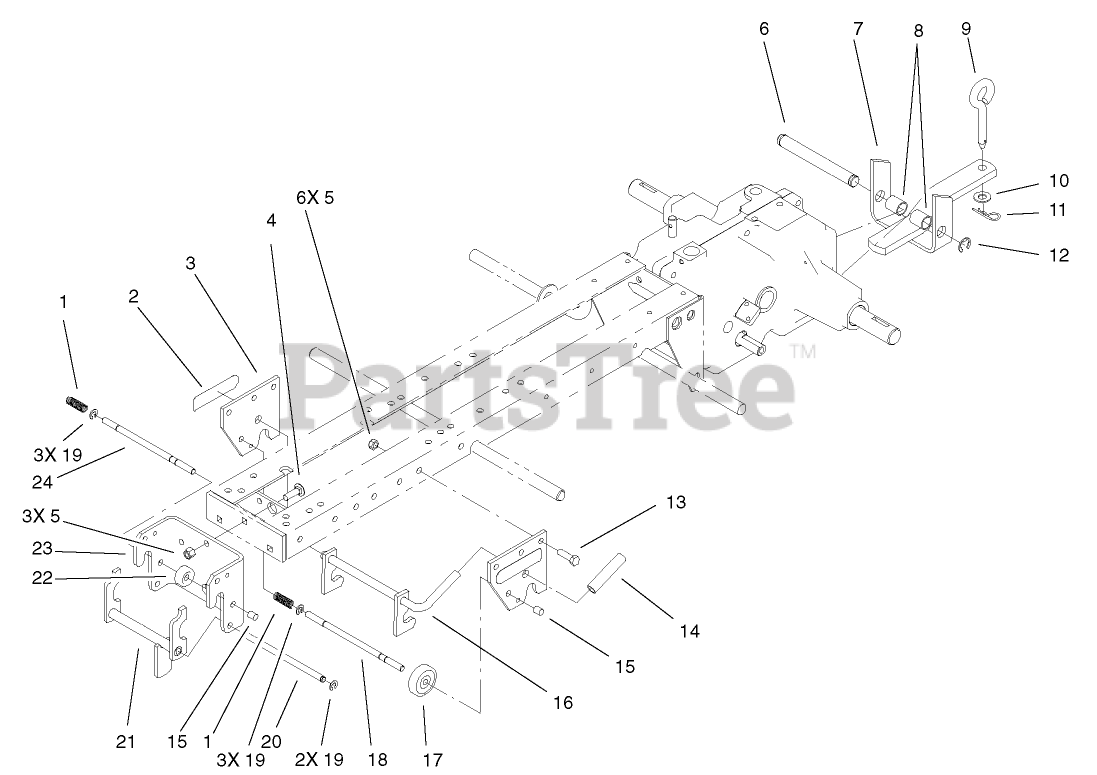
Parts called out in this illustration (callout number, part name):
1	SPRING
2	DECAL-ATTACH A-MATIC
3	PLATE-HITCH
4	BOLT-CARR
5	NUT-LOCK, NI
6	PIN-STATIONARY HITCH
7	HITCH ASM
8	SPACER
9	PIN-TOOL
10	WASHER-FLAT
11	PIN-HAIR
12	E-RING
13	SCREW-HH
14	GRIP
15	CAP-ROD, PLUNGER
16	MID HITCH ASM
18	ROD-LOCK
19	RING-RETAINING
20	ROD-LATCH PIVOT
21	LATCH
23	HITCH-FRONT
24	ROD-LOCK
